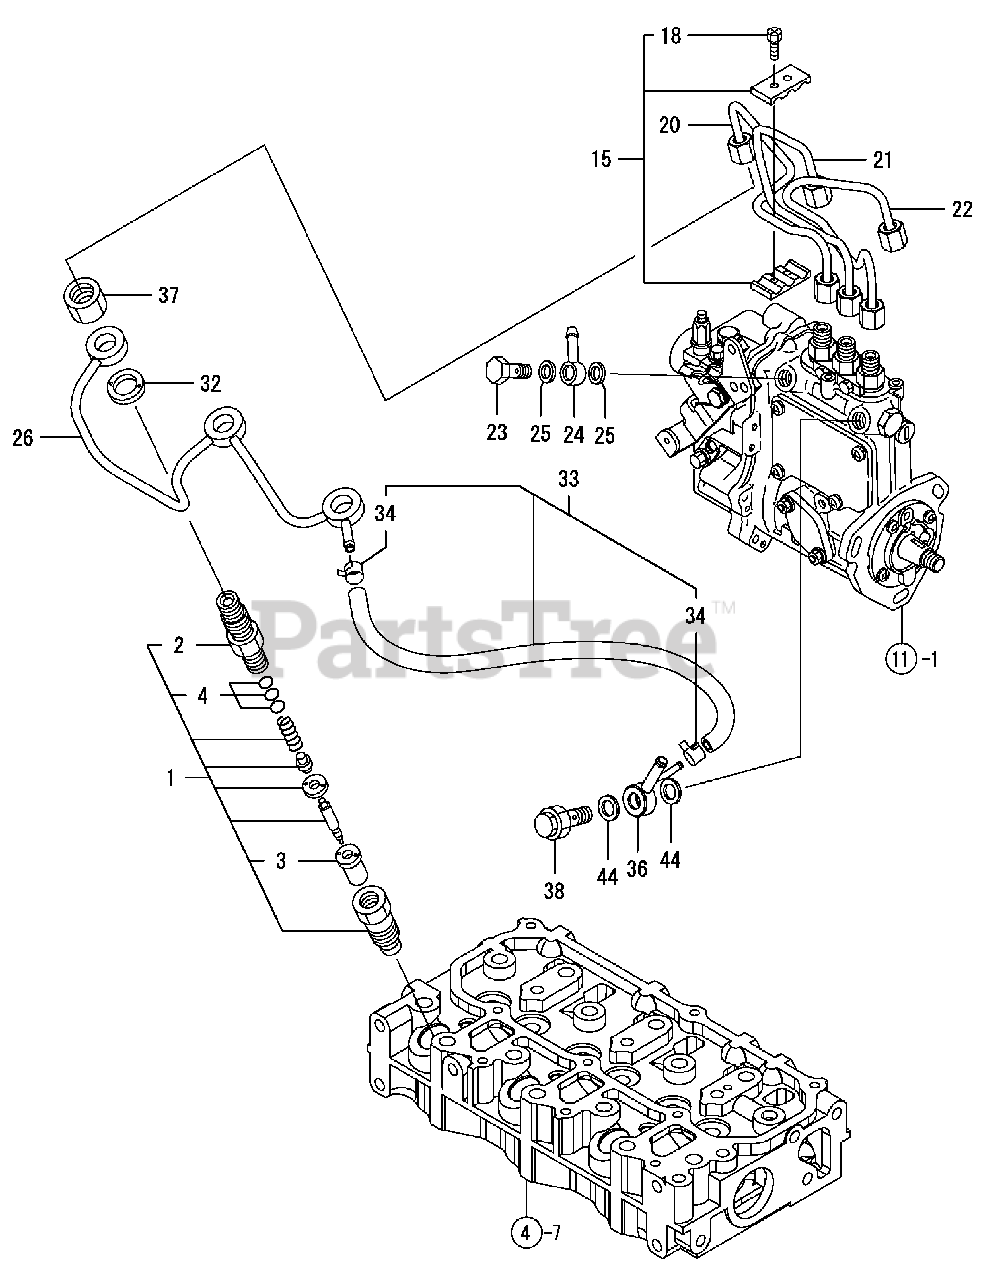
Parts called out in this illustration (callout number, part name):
1	VALVE ASSY,INJECTION
2	HOLDER, NOZZLE
15	RETAINER, INJ. PIPE
18	BOLT M4X14,HEX.SCKT.
20	PIPE, FUEL INJECTION
21	PIPE, FUEL INJECTION
22	PIPE, FUEL INJECTION
23	BOLT, PIPE JOINT
24	JOINT 12, PIPE
25	SEAL WASHER 12
26	PIPE ASSY, RETURN
32	GASKET, RETURN
33	PIPE, FUEL RETURN
38	VALVE ASSY, CHECK
44	SEAL WASHER 12
